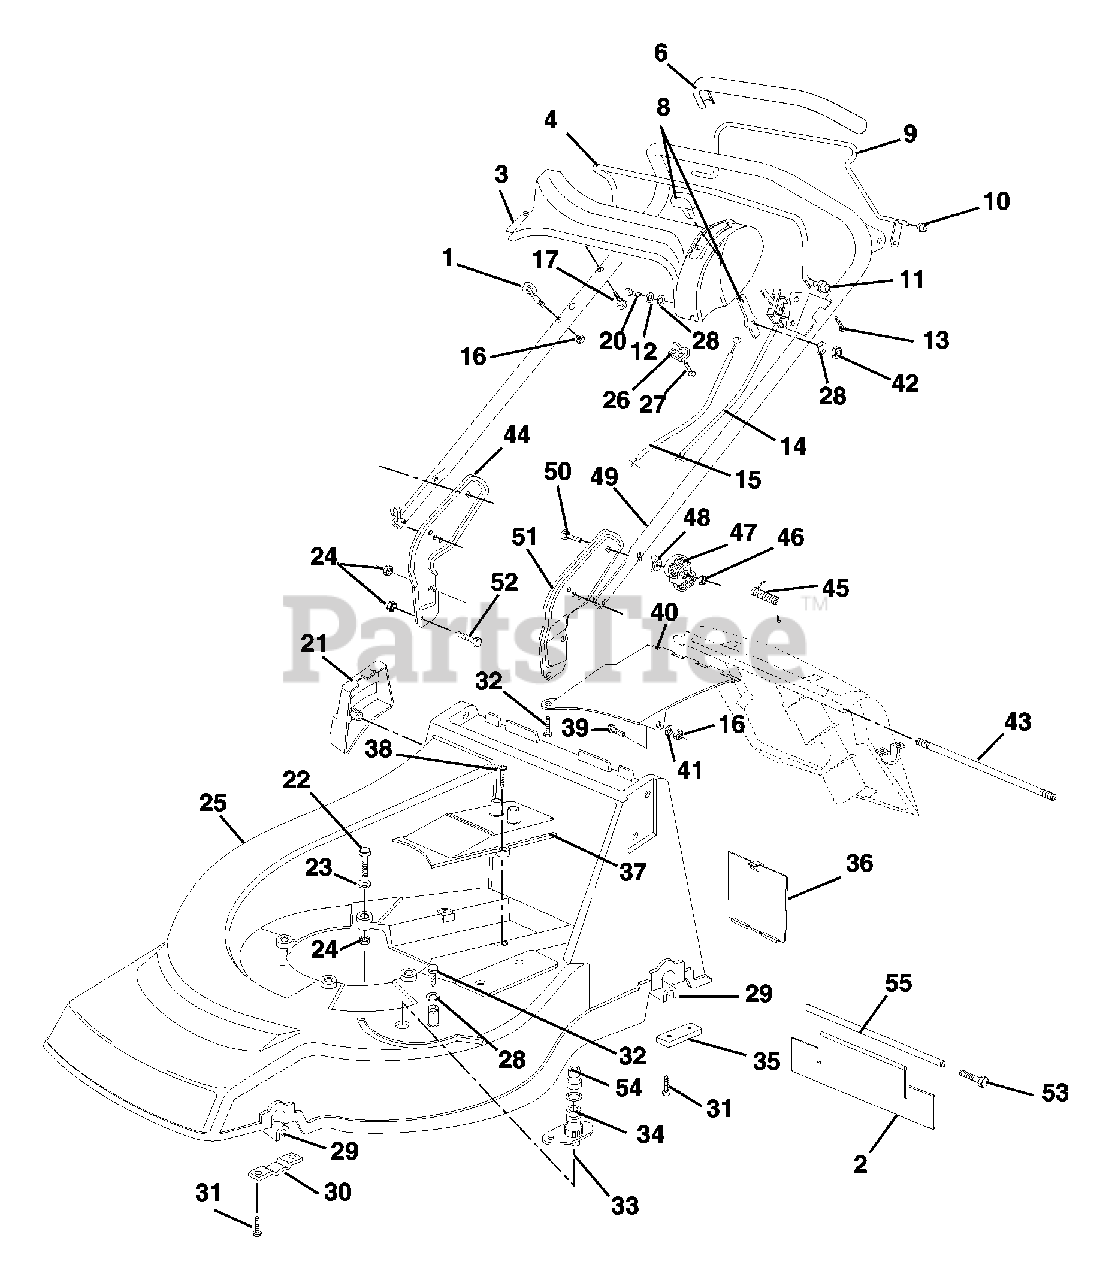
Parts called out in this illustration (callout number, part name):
1	GUIDE, ROPE
2	REAR PROTECTIVE GUARD, S.P.
3	DASHBOARD - BLACK
4	BAIL, ENGINE
6	GRIP, HAND BLACK
8	LEVER, THROTTLE W/KNOB
9	BAIL, TRACTION
10	BUSHING
11	BUSHING
12	WASHER M6
13	SCREW 4.8X38
14	CABLE, THROTTLE
15	CABLE, MOTOR BRAKE
16	NUT M5
20	SCREW M6X25
21	PROTECTION
22	SCREW M8X60
23	WASHER M8 8.4X16X1.6
25	21" DECK W/DECALS IMPORT
26	PLATE, DASHBOARD CABLE
27	SCREW 3.5X16
28	WASHER M6 6.6X18X2
29	BRASS, FRONT
30	PLATE, FRONT AXLE
31	SCREW 5.5X19
32	SCREW 5.5X16
33	WASHING CONNECTION
35	PLATE, REAR AXLE (SP)
36	DOOR, INSPECTION
37	PROTECTION, BELT
38	SCREW 5.5X19
39	SCREW M5X12
40	CONVEYOR
41	WASHER M5 5.5X15X1.6
44	BRACKET, HANDLEBAR RIGHT
46	NUT M8
49	HANDLEBAR, SELF-PROP
50	SCREW M8X55
51	BRACKET, HANDLEBAR LEFT
52	SCREW M8X25
54	Coupling, Hose
55	ROD, TRIALING SHIELD
